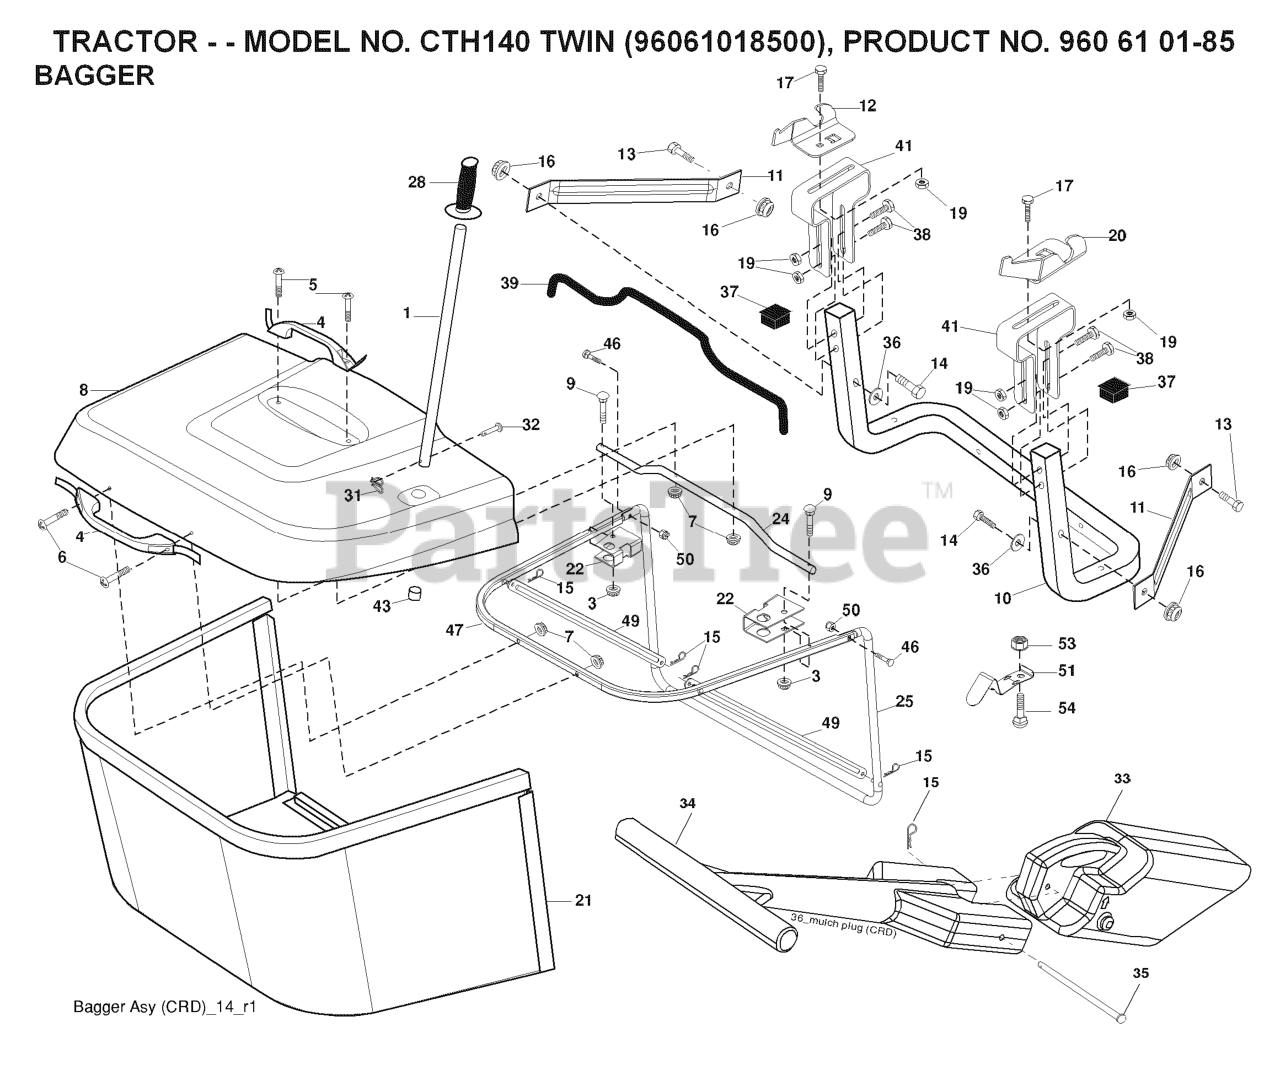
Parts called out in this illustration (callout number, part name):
1	TUBE HANDLE
3	NUT T
4	HANDLE.BAGGER.W/LVRS.BLK.CRD
5	SCREW.PAN.HEAD
6	REPL BY 532 75 00-29
8	COVER.PNT.BGR.CRD.WSLOTS.MS668
9	Bolt Carriage 1/4-20 x 2.25d x Gr.5
10	TUBE
11	BRACKET.SUPPORT.UPPER.BAG.CRD
12	BRKT PIVOT
14	BOLT-HEX EAK
15	RETAINER-SPRNG RB
16	NUT LOCK FLG 3/8-16 UNC
17	RP BOLT 5/16-18 X3/4 ZN/YEL GR
19	NUT LOCK HEX FLANGE 5/16-18
20	BRKT.PIVOT.RH.CRD
21	BAGGER.ASM.CRD.2007
22	BRKT.SIDE.BAG.CRD
24	TUBE.PIVOT.BAG.CRD.BLACK
25	PIPE
28	GRIP.HANDLE.BLACK
31	RETAINER CLIP
32	RIVET,DRILLED
33	PLUG.MULCHER.92 CRD
34	HANDLE.MULCHER.92.CRD (2 2)
36	WASHER
37	Plug Support Bagger CRD
38	BOLT.5/16-18X2.5
39	SEAL.TRIM.37'
41	BRKT.VERT.ADJ.BAGGER.CRD
43	PLUG, TUBING END
46	BOLT.CARRIAGE.5/16-18
47	PIPE
49	ROD
50	NUT.71038.31-18.HEX.NYLOCK
51	LATCH
53	NUT
54	BOLT
